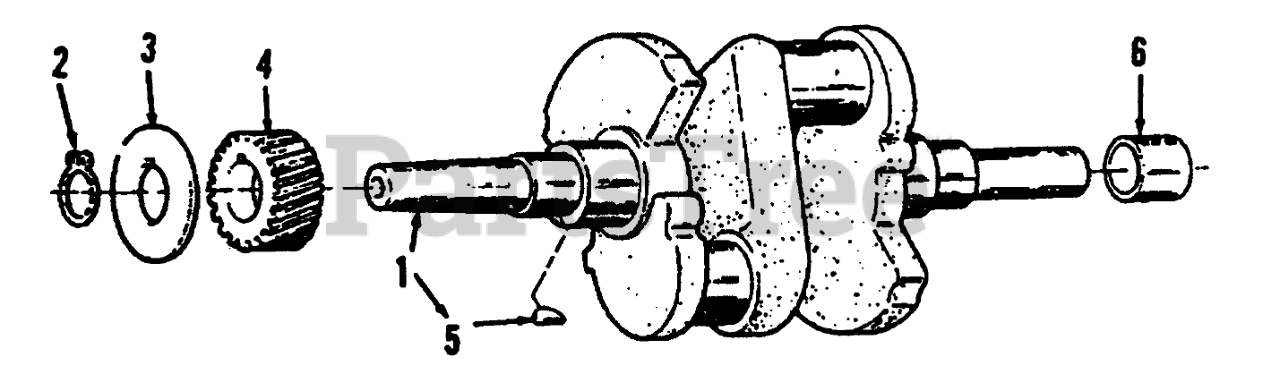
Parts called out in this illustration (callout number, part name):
1	CRANKSHAFT
2	Retaining Ring
3	Washer
4	Gear
5	Key
6	Cover-Valve
